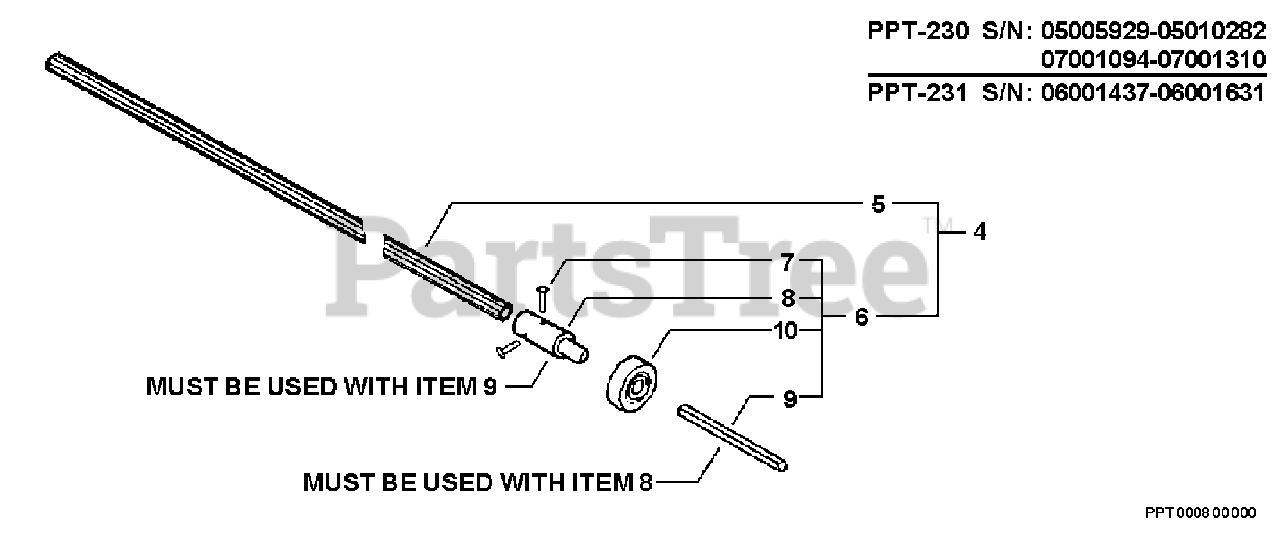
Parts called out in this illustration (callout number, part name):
4	DRIVESHAFT ASSY
5	DRIVESHAFT
6	SHAFT CONNECTOR KIT
8	CONNECTOR
9	SHAFT
10	BEARING, BALL 6002 DDU
